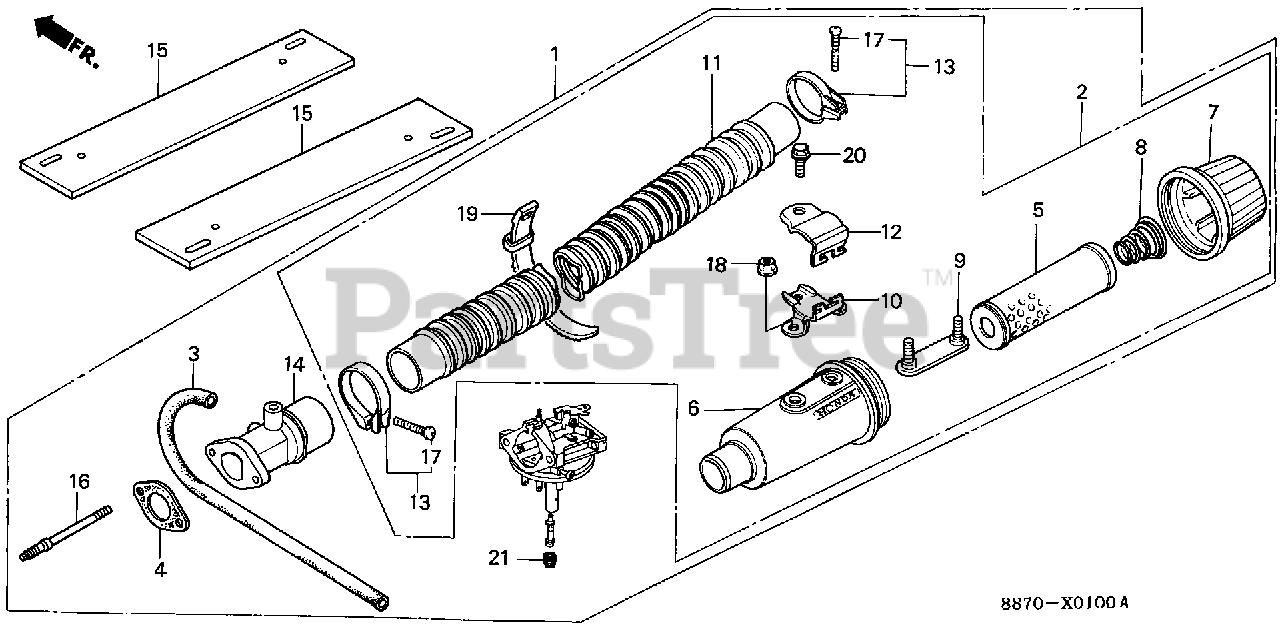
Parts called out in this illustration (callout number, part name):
1	AIR CLEANER KIT, SNORKEL (NOT AVAILABLE)
2	AIR CLEANER KIT, SNORKEL
3	TUBE, BREATHER
4	GASKET, AIR CLEANER
5	ELEMENT, AIR CLEANER
6	HOUSING, AIR CLEANER
7	CAP, AIR CLEANER
8	SPRING, SETTING
9	PLATE, AIR CLEANER SETTING
10	BRACKET A, AIR CLEANER
11	HOSE, AIR CLEANER
12	BRACKET B, AIR CLEANER
13	BAND, AIR CLEANER CONNECTING TUBE (34)
14	JOINT, TUBE CONNECTING
16	BOLT, STUD (6X95)
17	SCREW, PAN (4X25)
18	NUT, FLANGE (6MM)
19	BAND B3, WIRE
20	BOLT, FLANGE (6X16)
21	JET, MAIN (#65)
